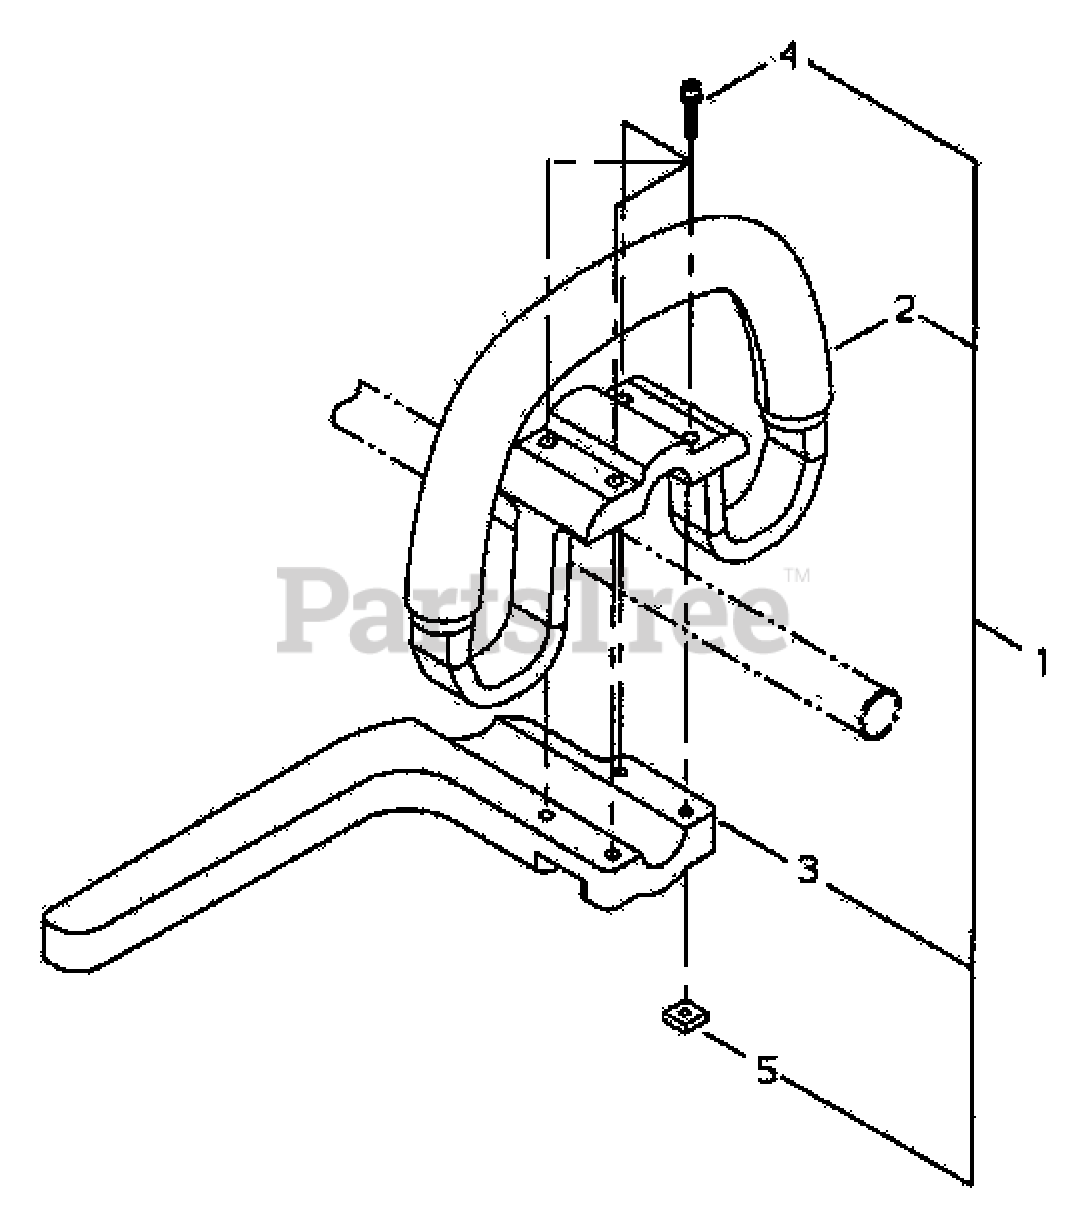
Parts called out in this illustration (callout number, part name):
1	HANDLE ASSY
2	HANDLE
3	BAR, BARRIER
4	SCREW - 5X35
5	NUT - 5
